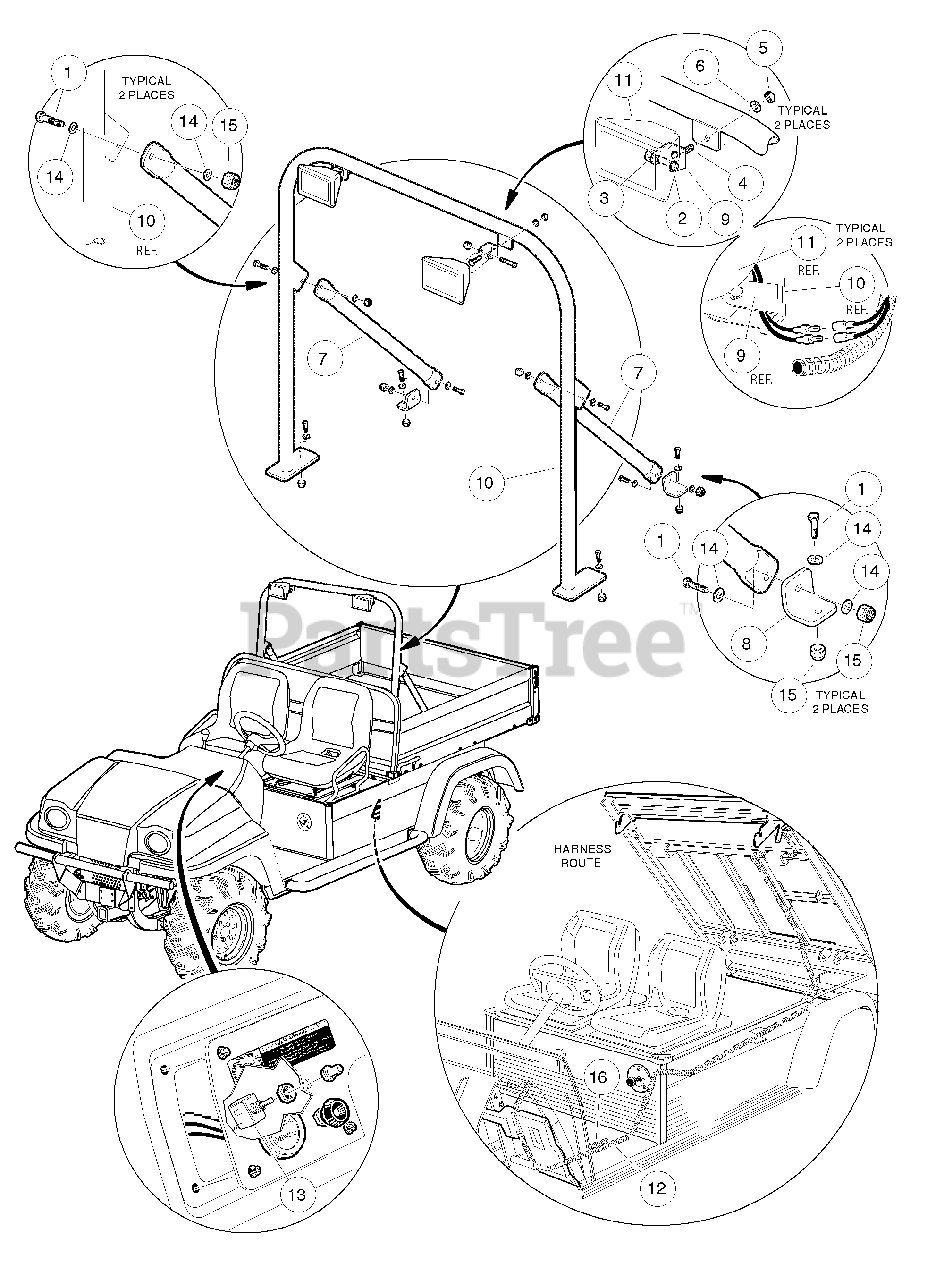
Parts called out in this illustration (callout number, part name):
1	Screw, 5/16-18 X 1.00 Hex Cap
2	Screw, M8 x 1.25 x 47, Hex Flange
7	Brace, Light Bar
8	Bracket, Brace Mtg
9	Bracket, Light Mtg
11	Light, Light Bar
12	Wire Harness, Light Bar
14	Washer, 5/16 Type A Flat
15	Locknut, 5/16-18 Nylon Insert
16	Tie Wrap, 8" Nylon
